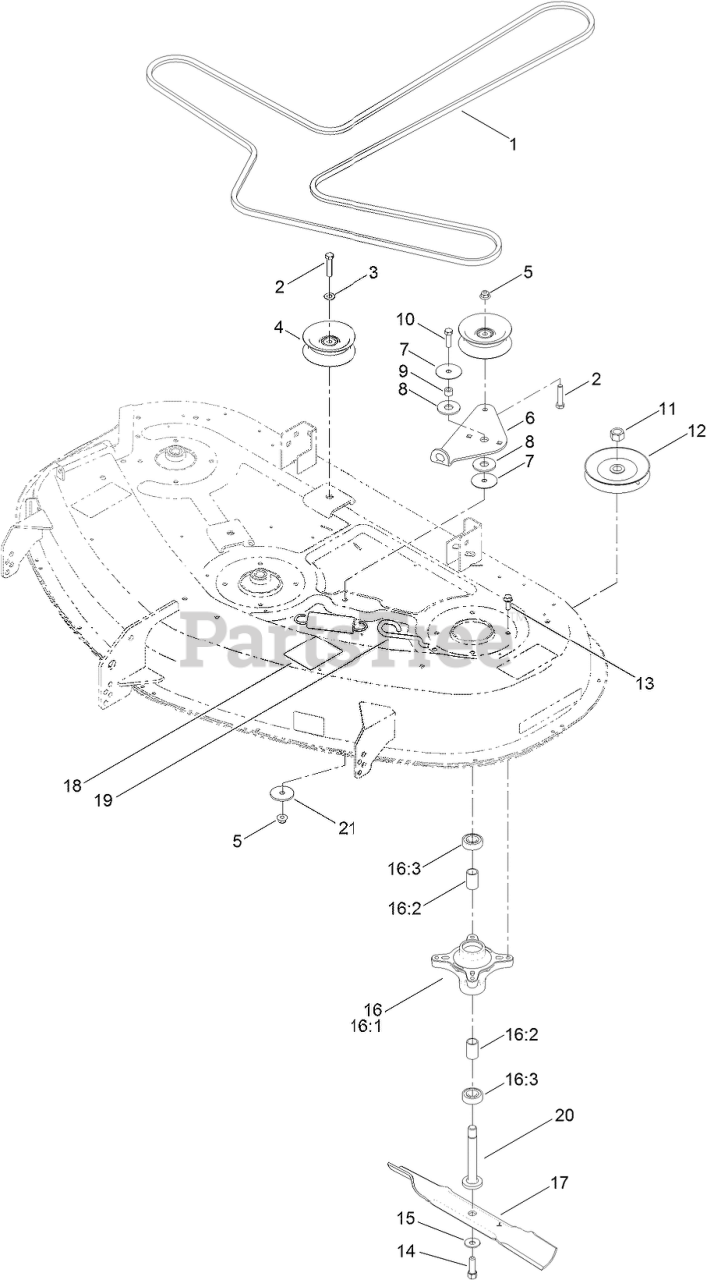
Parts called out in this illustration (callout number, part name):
1	V-BELT
2	SCREW-HH
3	WASHER-FLAT
4	PULLEY-IDLER, FLAT
5	NUT-HF, NI
6	ARM-IDLER
7	WASHER
8	WASHER-FRICTION, COMPOSITE
9	SPACER
10	SCREW-HH
11	NUT-HEX
12	PULLEY
13	SCREW-TAPTITE
14	SCREW-HH
15	WASHER-BELLEVILLE
16	SPINDLE ASM
16:1	SPINDLE
16:2	SPACER
16:3	BEARING-BALL
17	BLADE-MULCH, 17.50 INCH
18	SPRING-EXTENSION
19	HOOK-RETURN, SPRING
20	SHAFT-SPINDLE
21	WASHER-REBOUND
